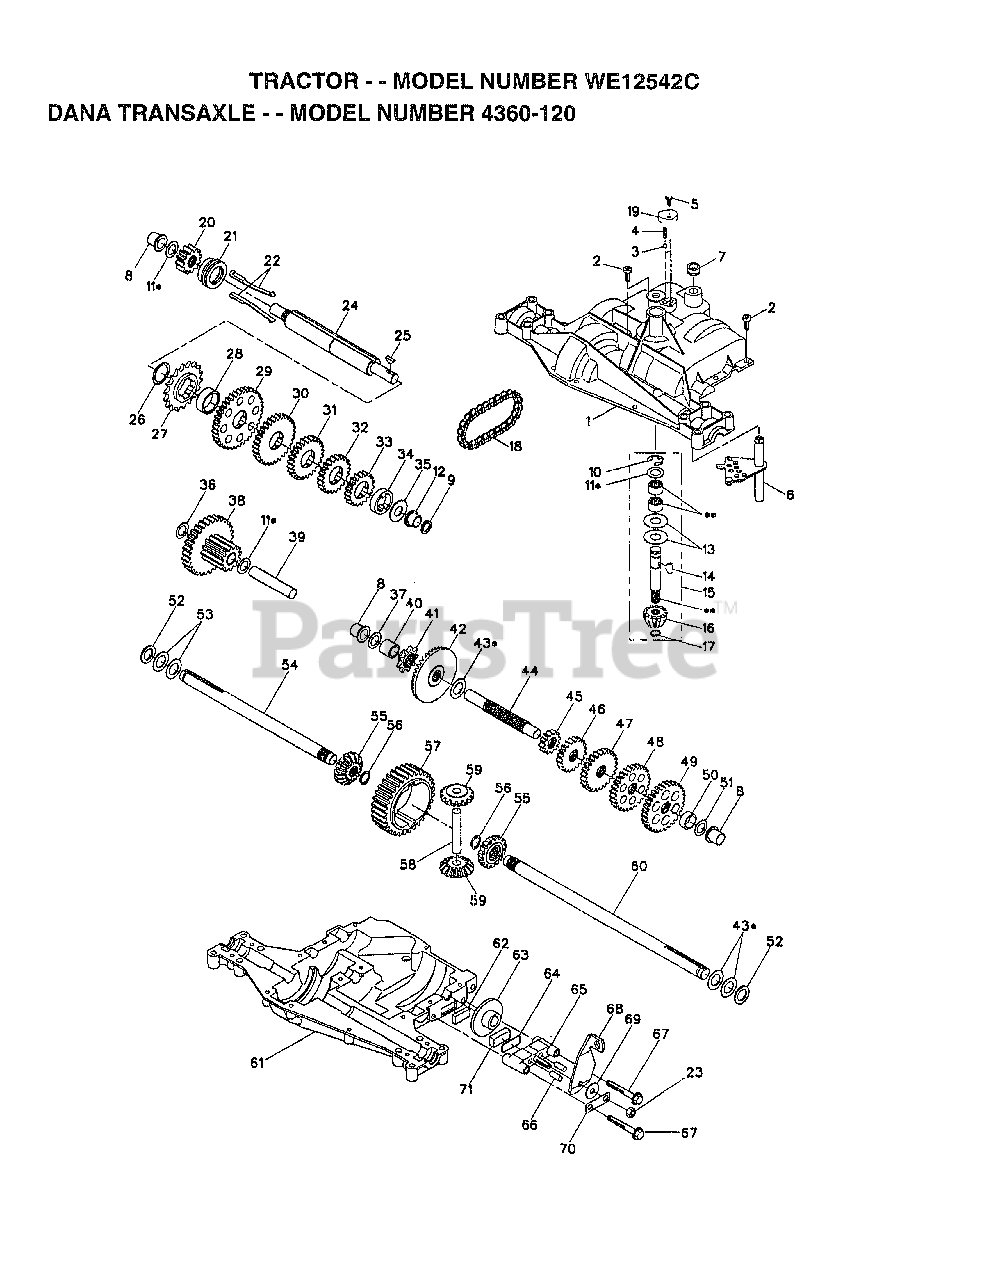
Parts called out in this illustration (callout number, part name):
1	HOUSING.UPPER.DANA.(5305J)
4	"SPRING, DETENT LT"
5	SCREW.TAPPING.1/4-20X.734
6	KIT SHIFTER ASM
9	SEAL.OIL.DAN.5508
10	RETAINING RING LT
11	ASM KIT SHIM 4689
12	BEARING.FLNG.5511
13	WASHER T
14	KEY WOODRUFF-DANA
15	INPUT SHAFT KIT 6250
16	PINION.BEVEL.12T(5620)
17	"RING,RETAINING LT"
18	"CHAIN,24 PTCH LT"
19	COVER.DETENT.(5584)
20	GEAR.SPUR.12T.(5627)
21	CLUTCH.COL.5467
22	ASM KIT CLTCH KEY
23	NUT.LOCK.5/16-24
24	SHAFT INTERM DANA
25	WOODRUFF KEY
26	"RING,RETAINING LT"
27	SPROCKET 18T T
28	SPACER YT
29	GEAR SPUR 37 TTH
30	GEAR SPUR 30T
31	GEAR 25T LT
32	GEAR SPUR 22 TT
33	SPUR GEAR 19T
34	SPACER
35	"WASHER, PLAIN LT"
36	WASHER 045
37	WASHER 031
38	ASSY.GEAR.6153 12T&30T
39	SHAFT IDLER
40	SPACER T
41	SPROCKET 9T LT
42	GEAR.BEVEL.36T(5621)
43	ASM KIT SHIM
44	SHAFT T
45	GEAR SPUR 12 TTH
46	GEAR SPUR 20T
47	"GEAR, SPUR 25T LT"
48	GEAR 28T T
49	"GEAR, SPUR 31T LT"
51	WASHER 060
52	NEOPRENE WASHER
53	WASHER 031
54	AXLE.LH(5528-1)
55	MITER 5270 12T.SPLINED
56	RING.RETAINING.(5270)
58	SHAFT T
59	MITER 5623.12T.IDLER
60	AXLE.RH.(5528-2) DANA
61	HOUSING LOWER TNS
62	PUCK T
63	BRAKE DISC. T
64	SPACER LT
66	PIN T
67	SCREW.(5562) .5/16-18X2.35
69	WASHER LT
70	BRACKET, ANTI-ROTATION
71	PUCK T
